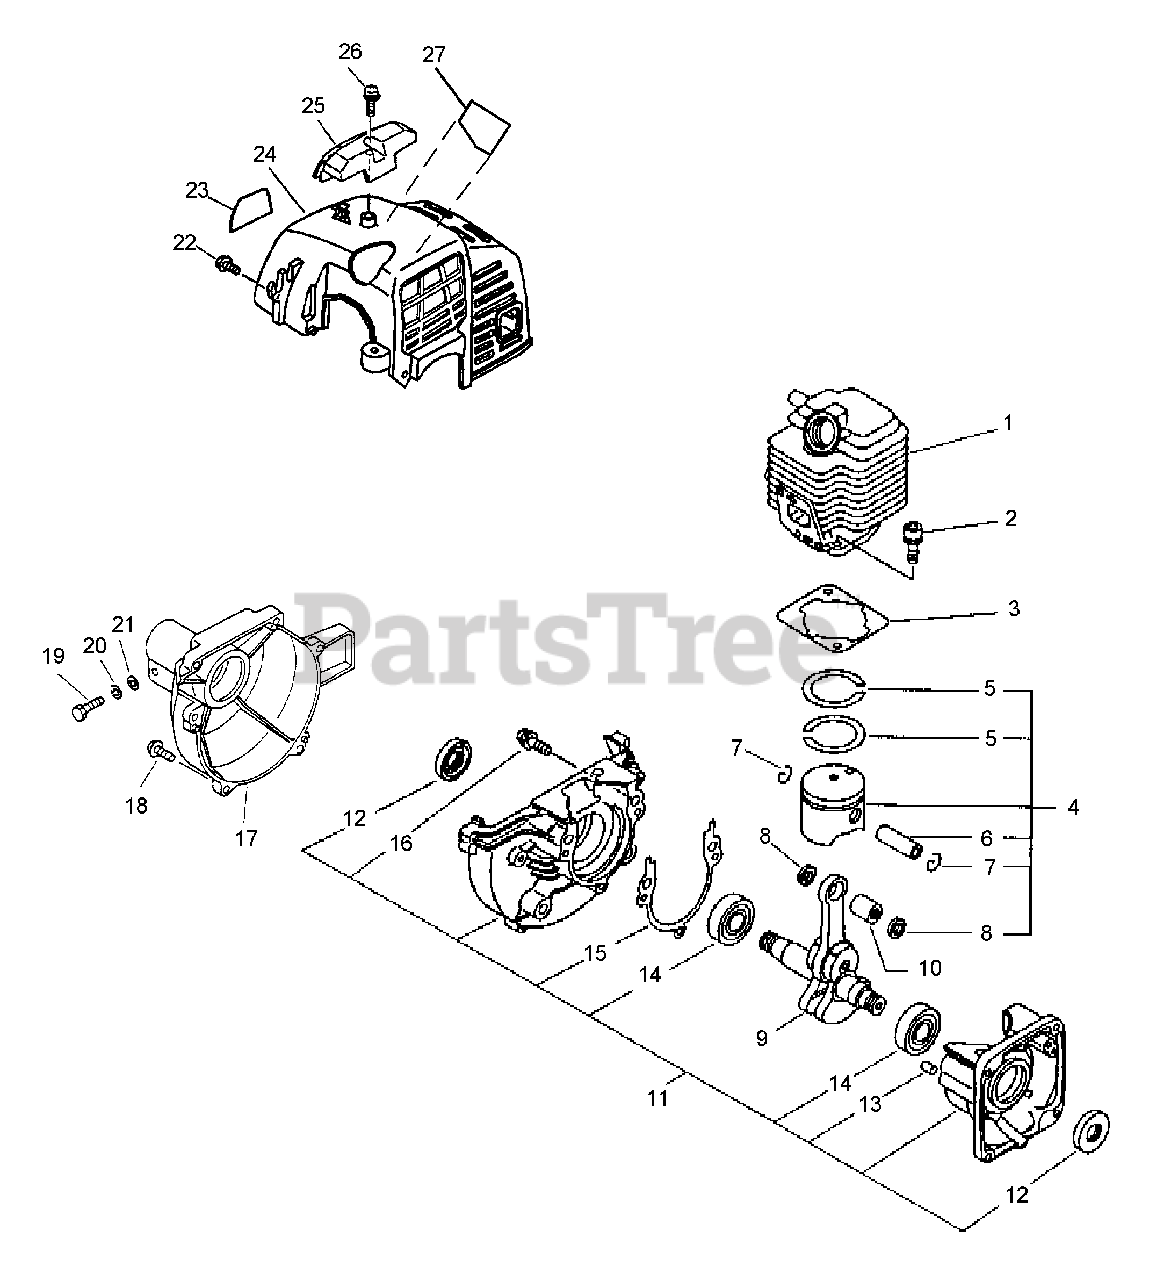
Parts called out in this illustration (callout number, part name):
1	CYLINDER
2	SCREW - 5X22
3	GASKET, CYLINDER
4	PISTON KIT
5	RING, PISTON
6	PIN, PISTON
7	RING, RETAINING
8	SPACER, PISTON
9	CRANKSHAFT ASSY
10	BEARING, NEEDLE
11	CRANKCASE ASSY
12	SEAL, OIL
13	PIN - LOCATING
14	BEARING, BALL - 6201
15	GASKET, CRANKCASE
16	SCREW - 5X28
17	CASE, FAN - ORANGE
18	SCREW - 4X16
19	BOLT - 5X25
20	LOCKWASHER - 5
21	WASHER - 5
22	SCREW - 4X12
23	LABEL - MODEL
23	LABEL - MODEL PPF-2110
24	COVER, ENGINE - ORANGE
25	GUARD, TOP - BLACK
26	SCREW - 5X16 -- TAPPING
27	LABEL - CAUTION
